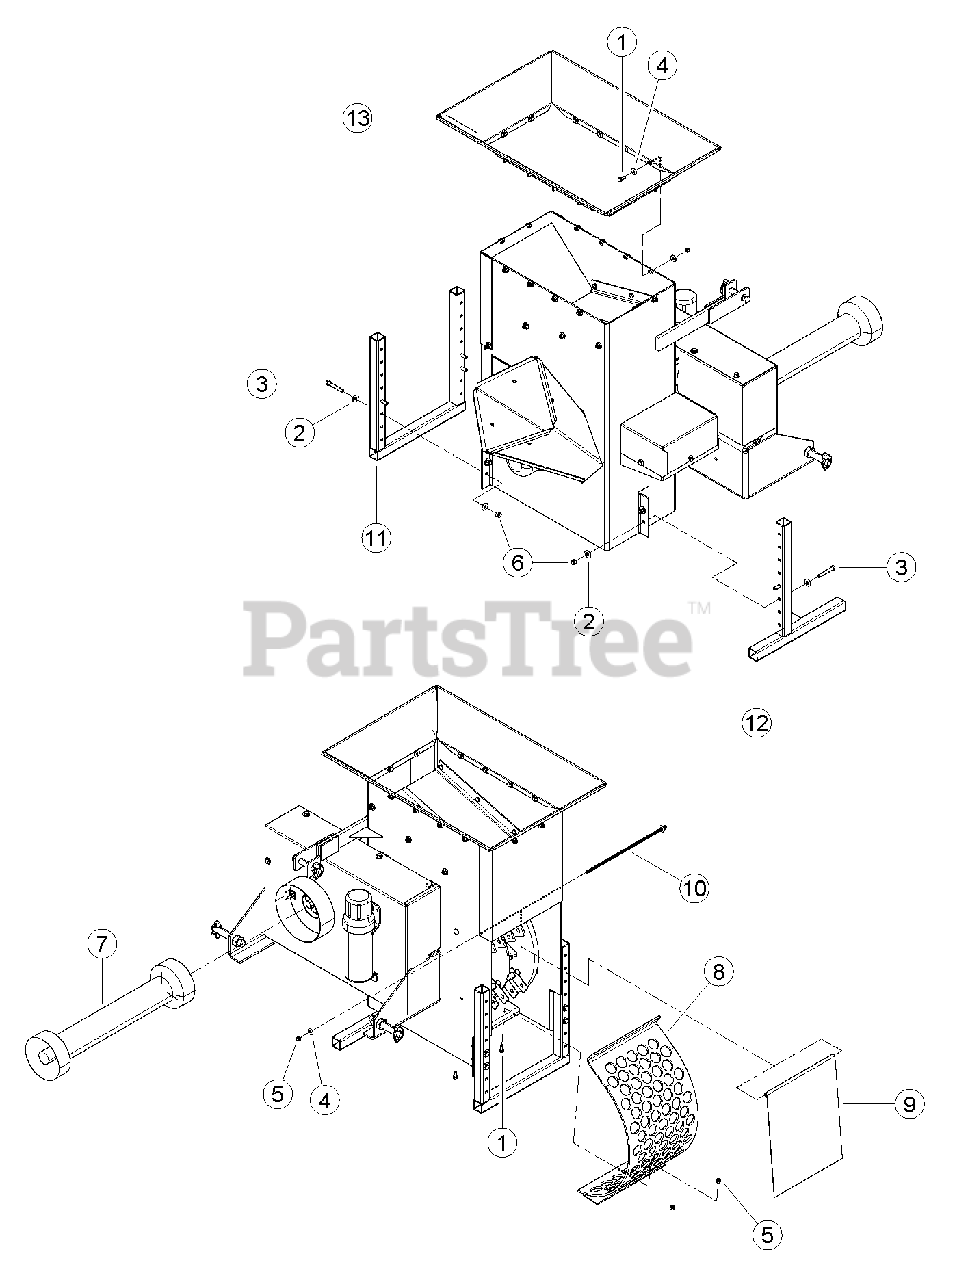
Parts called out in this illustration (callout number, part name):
1	BOLT, 5/16 X 3/4 HEX HD GR5 ZP
2	WASHER, 3/8 FLAT ZP
3	BOLT, 3/8 X 2-1/2 HEX HD GR5 ZP
4	WASHER, 5/16 FLAT ZP
5	NUT, 5/16 NE NYLOCK ZP
6	NUT, 3/8 NE NYLOCK ZP
7	DRIVESHAFT, 540 C/S WS
8	WELDMENT, LARGE SCREEN COARSE
9	DOOR, COMMERCIAL DISCHARGE
10	ROD, DOOR PIVOT
11	WELDMENT, PTO C/S STAND
12	WELDMENT, PTO C/S POST
13	ASSEMBLY, HOPPER W/ DECALS
